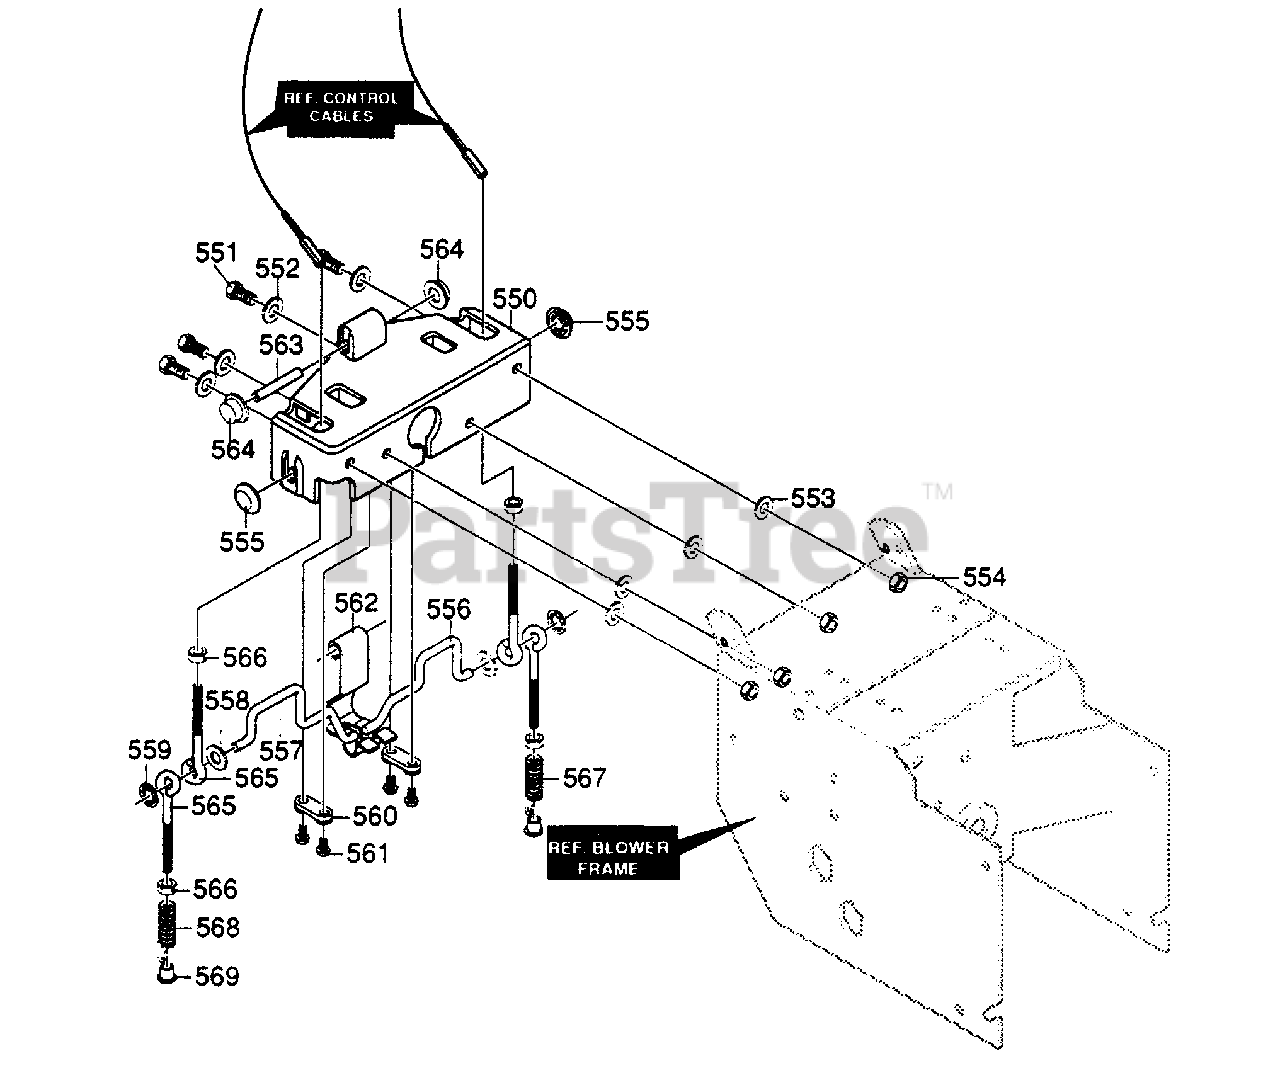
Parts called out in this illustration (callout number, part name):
550	HOUSING, SINGLE HAND CONTL
551	SCREW 5/16-18X.75
552	FLATWASHER .344X.69X.065
553	WASHER HVSPTLK.328X.60X.09
554	NUT, 5/16-18 REGHEX
555	NUT, PUSH ON CAP
556	CAM/LATCH LH
557	CAM/LATCH RH
558	FLATWASHER, .344x.69x.065
559	RING, RETAINING
560	CLAMP, SHC CAM FRAME MTD
561	SCREW #8X.75 PANTAPPLASTIC
563	PIN, SPRING PIVOT
564	NUT, PUSH ON 3/8"
565	EYE BOLT, 10-24X2.50
566	NUT, #10-24 REGH
567	SPRING, DRIVE CLUTCH 2.75
568	SPRING, AUGER CLUTCH 2.38
569	NUT, 10-24 T
